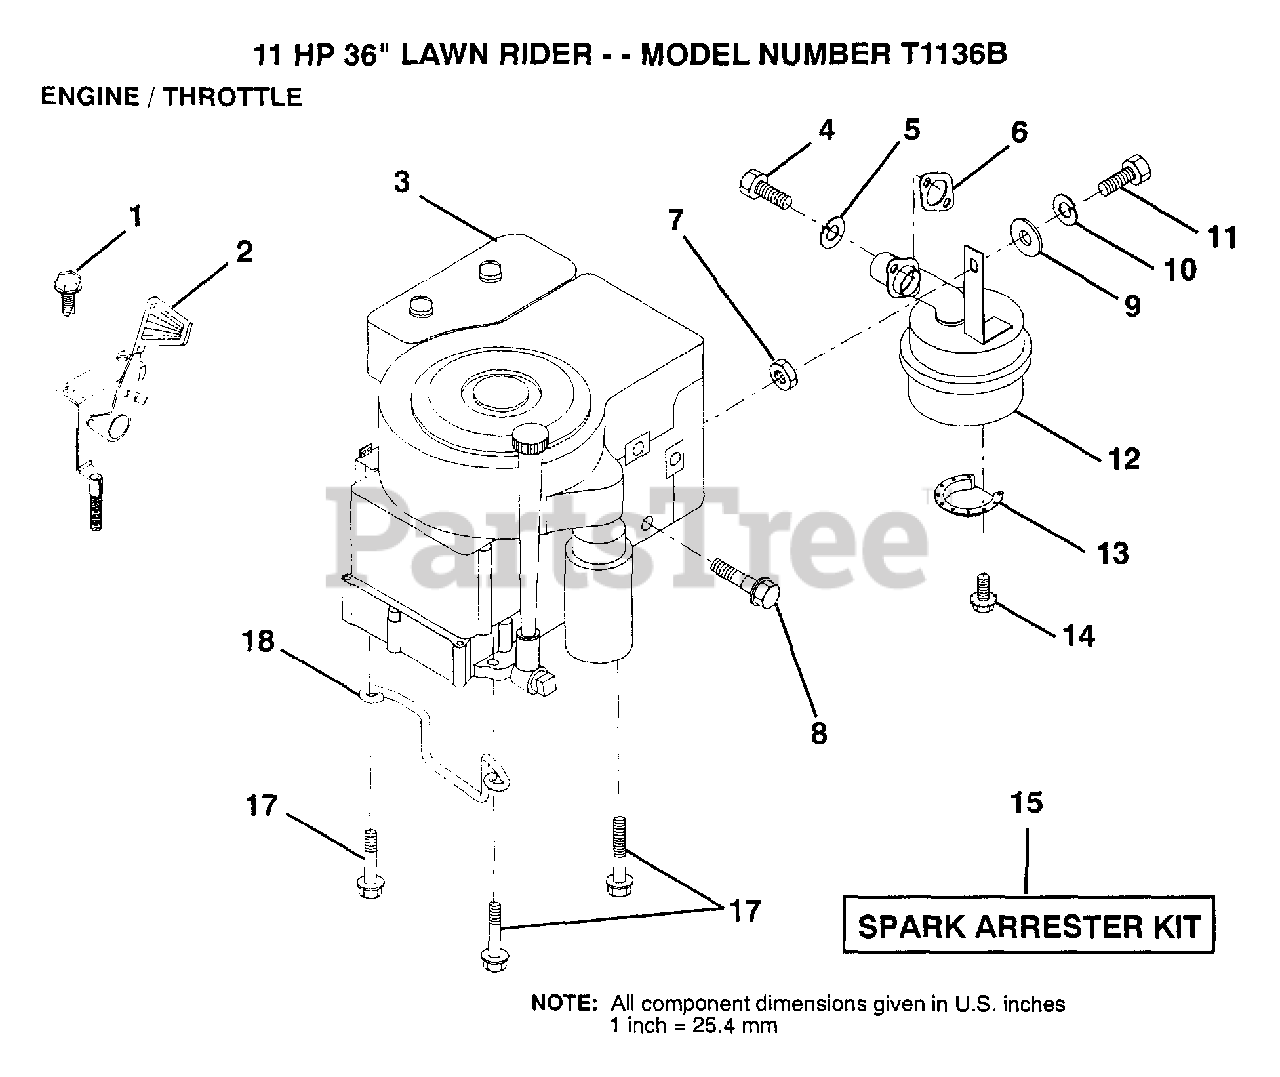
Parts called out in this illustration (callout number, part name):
1	SCREW
2	THROTTLE CONTROL
4	SCREW
5	LOCKWASHER
7	NUT.HEX.5/16-18
8	BOLT T
10	LOCKWASHER
11	BOLT
12	MUFFLER
13	DEFLECTOR.222573
17	SCREW LT
18	"KEEPER,DR BELT GR"
